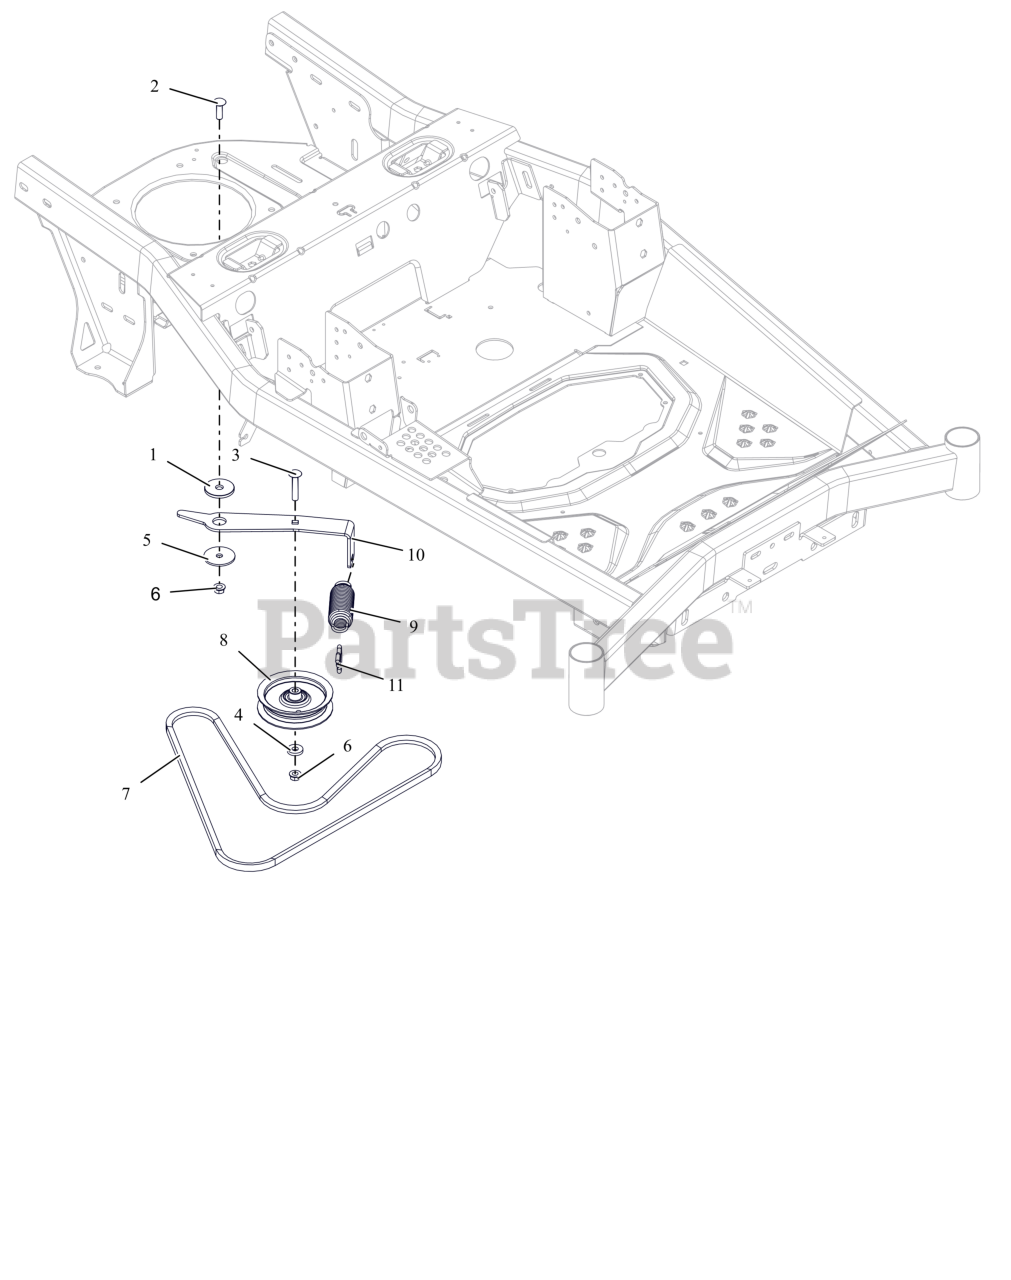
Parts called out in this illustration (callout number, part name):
1	BSHG-FLG .406X.88X.43X.25
2	BLT,RHSSN .38-16X1.25 G5 ZCC
3	BLT,RHSSN.375-16X2.00 G5 ZCC
4	WSHR, FLT .406X1.00X.188 ZCC
5	WSHR-FL-STL 0.406X2X0.125 ZCC
6	NUT-LK-CTR-FLG .375-16 GF ZCC
7	V-BELT, A-RAW EDGE COGGED
8	IDLER, FLAT - 4.06" X .75"
9	SPRG, EXTENSION
10	ARM- GROUND DRIVE IDLER
11	HOOK- WIRE FORMED SPRING
